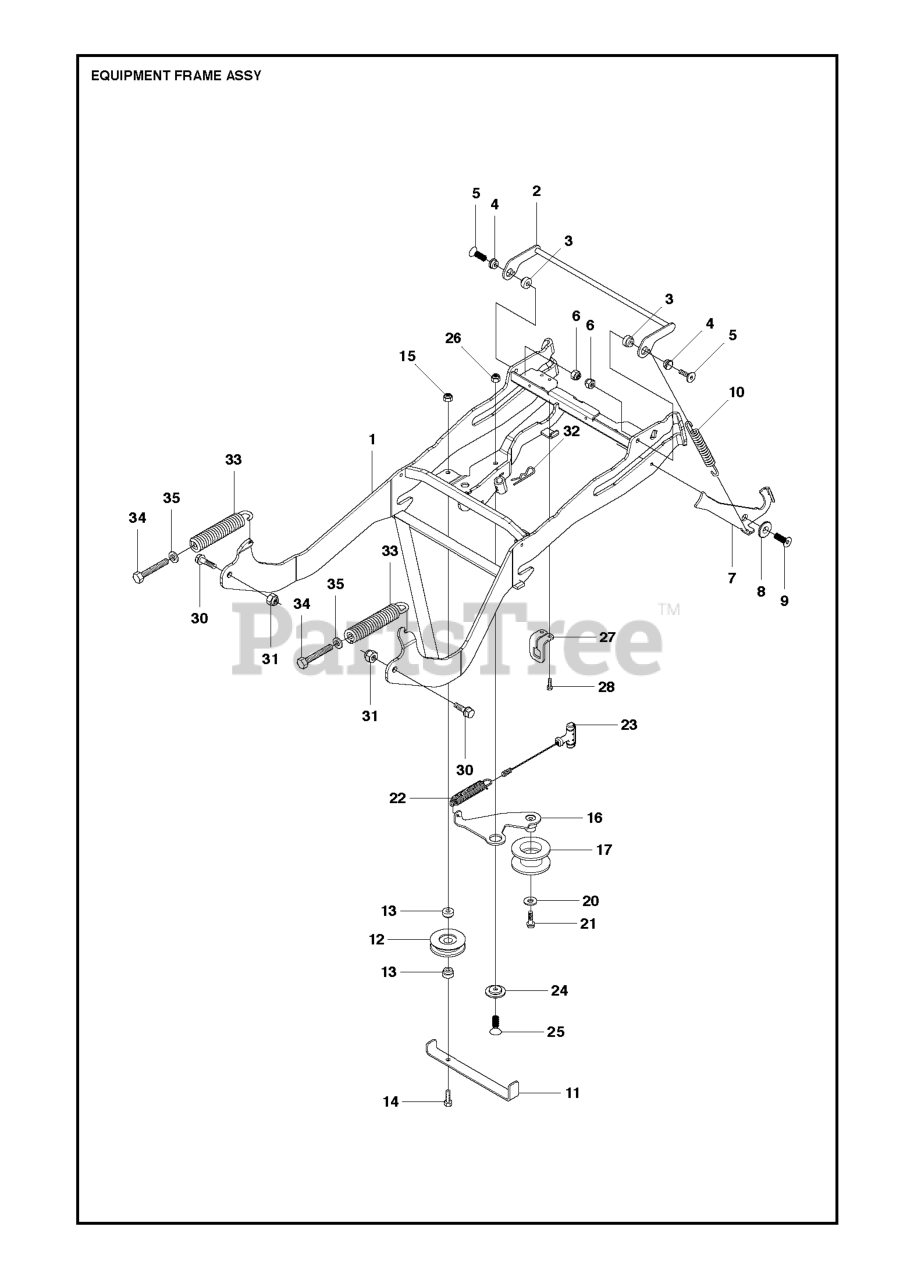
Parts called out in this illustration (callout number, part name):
6	LOCKNUT M8
8	WASHER
8	SPACER
9	SCREW IHCSFM
12	PULLEY ASSY
14	SCREW
15	LOCKNUT M8
17	BELT TENSIONER WHEEL ASSY
18	BALL BEARING 6004-2RS1
19	RETAINING RING
24	WASHER
24	WASHER SHOULDER ASSY
26	LOCKNUT M8
28	SCREW
28	BOLT FLANGE - M6X20
29	LOCKNUT M6
35	WASHER
